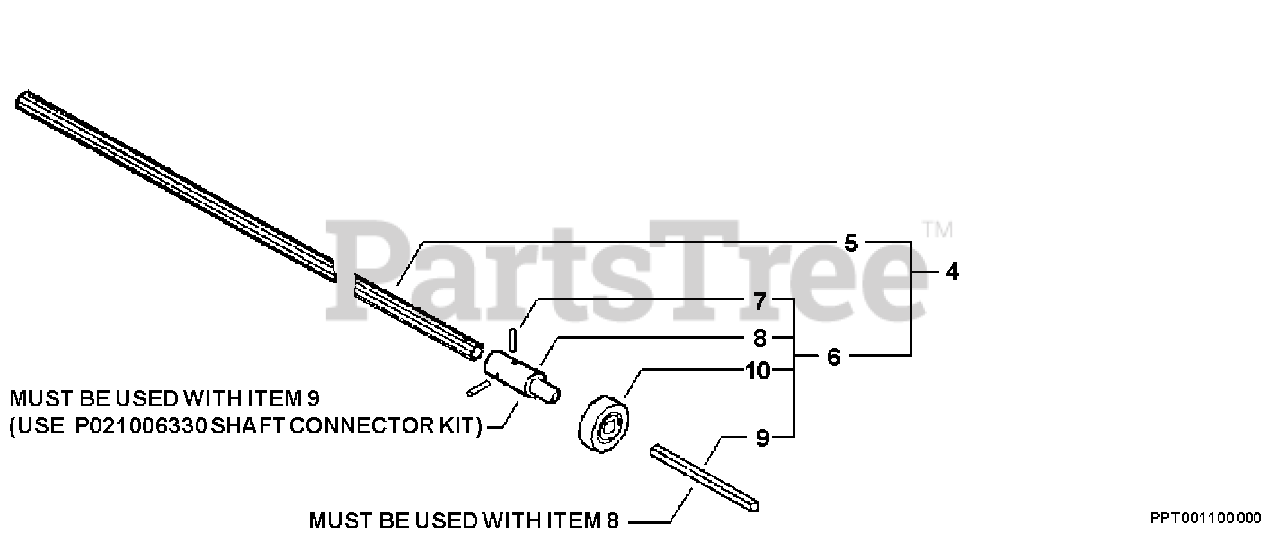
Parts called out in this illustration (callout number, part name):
4	DRIVESHAFT ASSY
5	DRIVESHAFT
6	SHAFT CONNECTOR KIT
8	CONNECTOR
9	SHAFT
10	BEARING, BALL 6002 DDU
